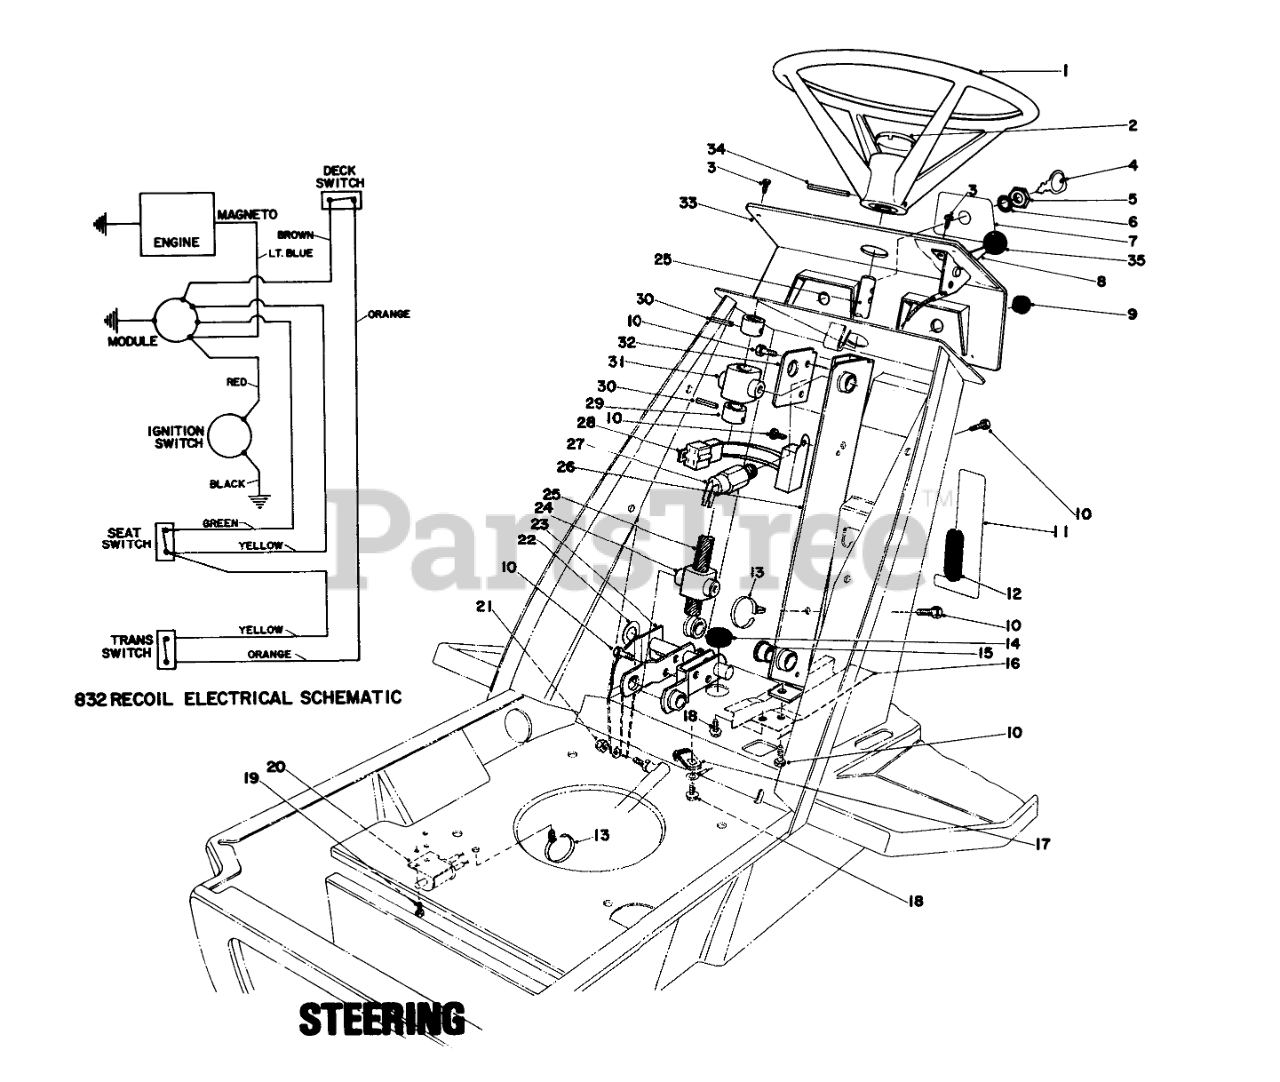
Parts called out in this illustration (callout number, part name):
1	Steering Wheel
2	Insert-Steering Wheel
3	SCREW-HWHTF
4	Key
5	NUT-HH
6	WASHER-TOOTH, INTERNAL
7	DASH PANEL DECAL
8	THROTTLE CONTROL
9	Domed Plug
10	SCREW-HWHTF
11	Decal-Deck
12	EDGE MOULDING
13	TIE-MOUNT, PUSH
14	GROMMET
15	BEARING-FLANGE
16	WIRE HARNESS SHLD B
17	CLIP-FUEL LINE
18	SCREW-HWH
19	SCREW-TAPTITE
20	DECK INTERLOCK SWITCH
21	Nut
22	WASHER
23	STEERING LINK WA BO
24	FOLLOWER STEER SHAFT
25	STEERING SHAFT
26	STRG BRKT B
27	Ignition Switch (Incl. Ref. #4-6)
28	INTERLOCK MODULE
29	STRG SHAFT COLLAR
30	PIN-SPRING
31	BRG STEERING SHAFT
32	STRG BRG SUPPORT
33	DASH PANEL
34	PIN-ROLL
35	KNOB-CONTROL
